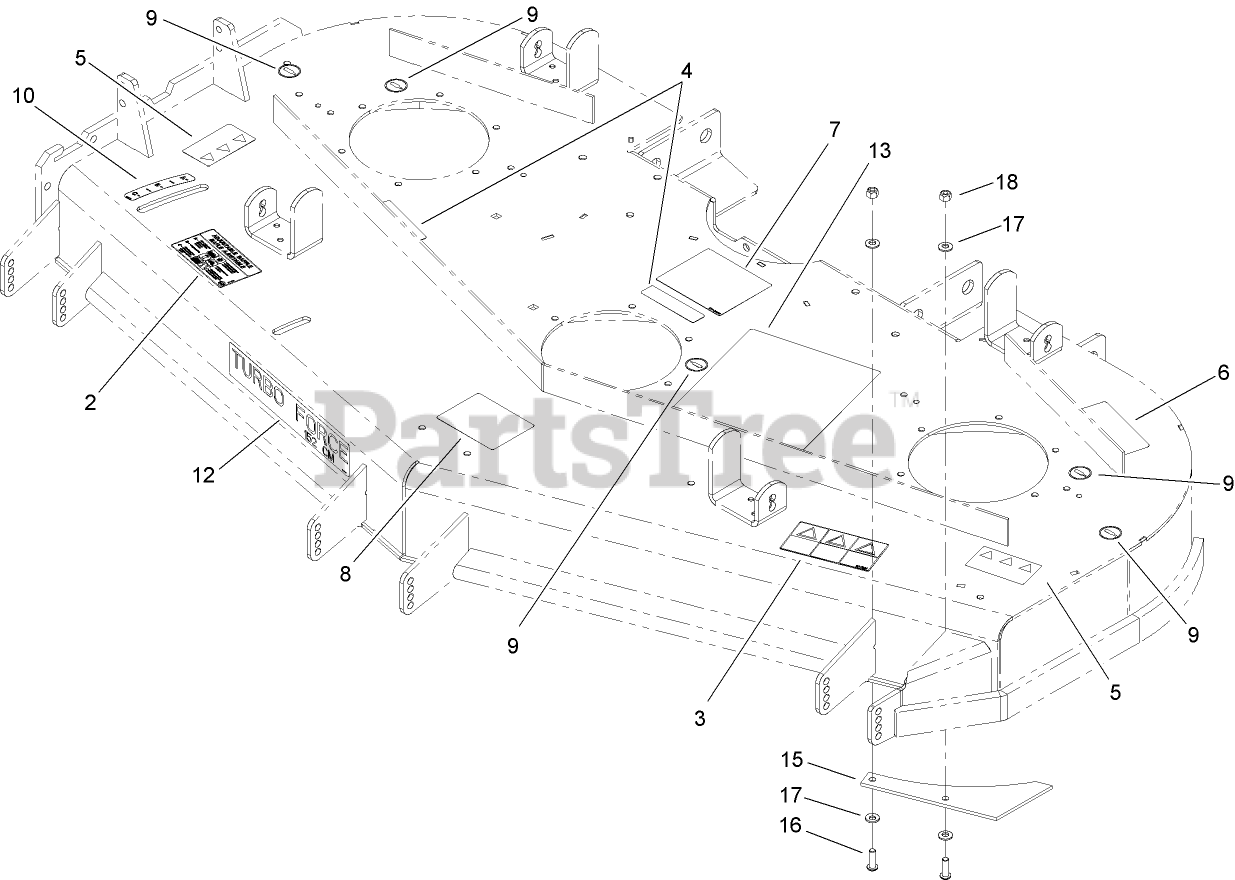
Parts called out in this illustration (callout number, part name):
2	DECAL-ADJUSTMENT, BAFFLE
3	DECAL-DANGER
4	DECAL-WARNING
5	DECAL-DANGER
6	DECAL-TORQUE, BLADE BOLT
7	DECAL-ROUTING, BELT
8	DECAL-ANTI SCALP
9	DECAL-GREASE
10	DECAL-SETTING, BAFFLE
13	DECAL-SERVICE, CHECK
15	PLATE-TURBO
16	SCREW-HSBH
17	WASHER-SPRING
18	NUT-LOCK, NI
